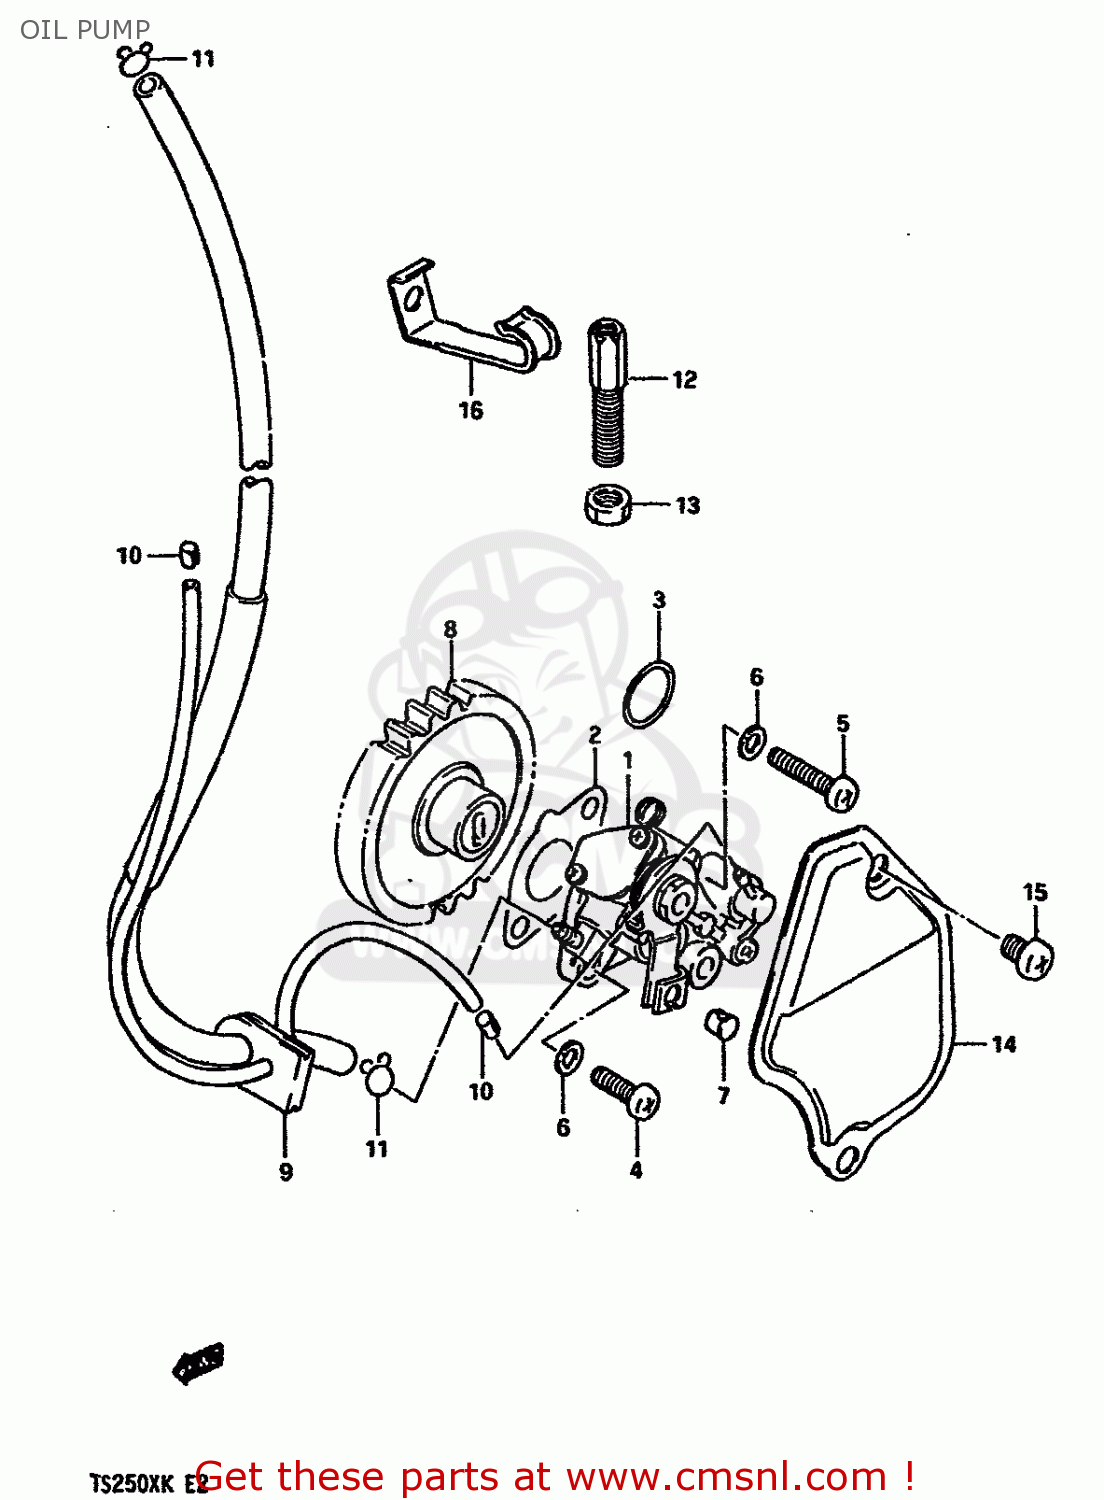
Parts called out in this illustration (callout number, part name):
1	PUMP ASSY,OIL
2	GASKET,OIL PUMP (NAS)
3	O RING(D:1.5,ID:19.5)
4	SCREW
5	SCREW
6	LOCK WASHER
7	TERMINAL,CABLE
8	GEAR,OIL PUMP DRIVEN
9	HOSE,OIL
10	CLIP
11	CLIP
12	BOLT
13	NUT
14	CAP,OIL PUMP INSPECTION
15	SCREW
16	CLAMP
